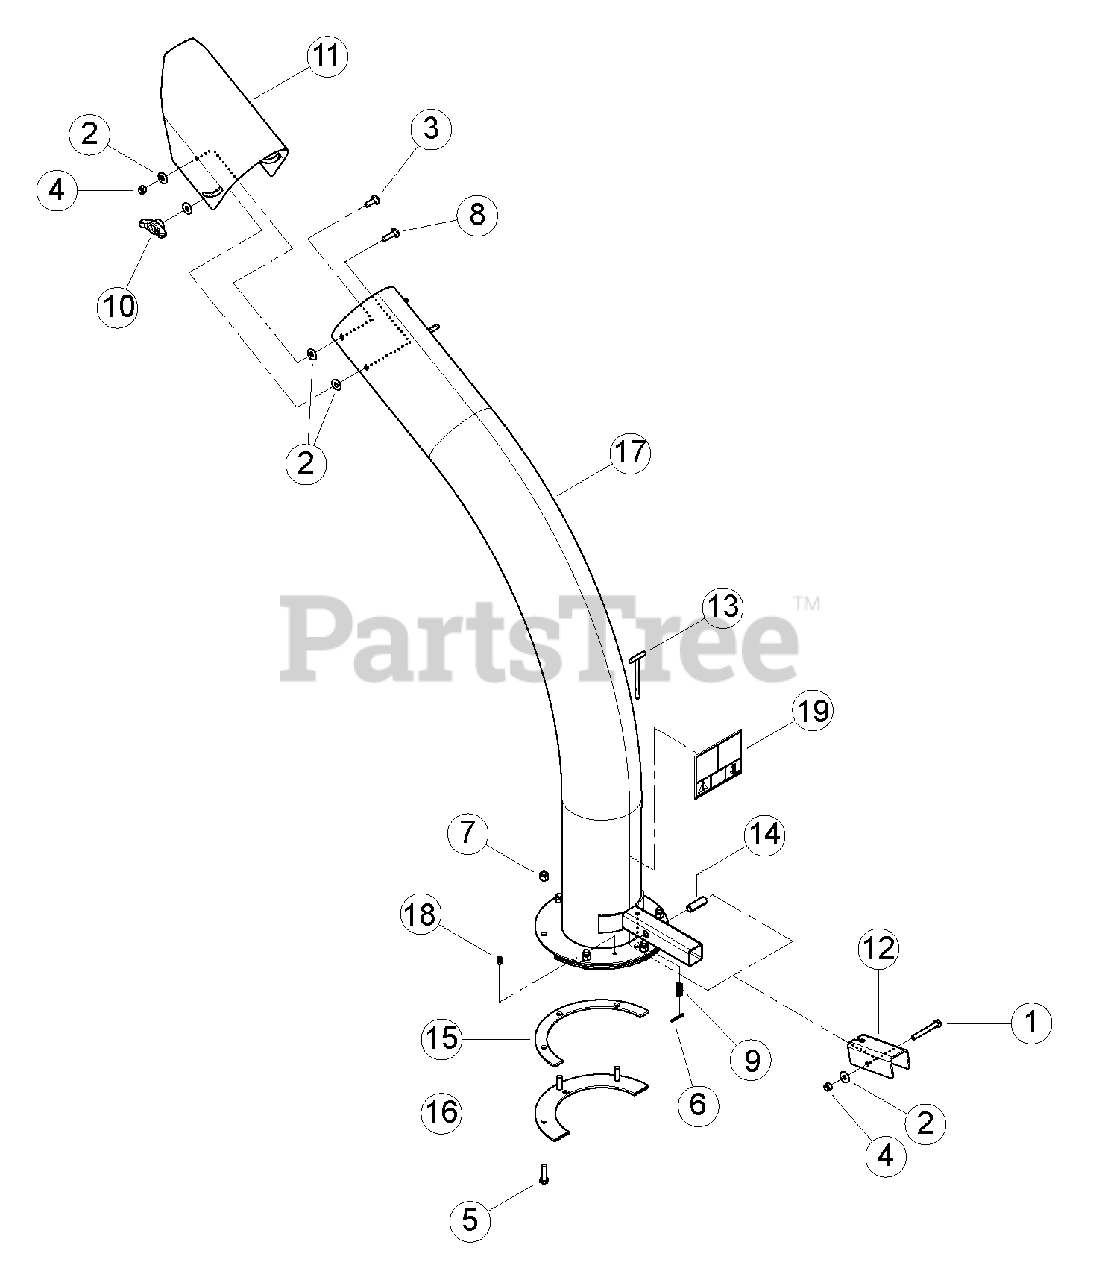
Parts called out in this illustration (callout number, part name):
1	BOLT, 5/16 X 2-1/2 HEX HD GR5 ZP
2	WASHER, 5/16 FLAT ZP
3	BOLT, 5/16 X 1 CRG GR5 ZP
4	NUT, 5/16 NE NYLOCK ZP
5	BOLT, 3/8 X 1-1/4 HEX HD GR5 ZP
6	PIN, 1/8 X 1.00 COTTER ZP
7	NUT, 3/8 NE NYLOCK ZP
8	BOLT, 5/16 X 1-1/4 CRG GR5 ZP
9	SPRING, LOCK COMPRESSION
10	KNOB, 5/16-18 UNC TEE W/LOCKING INSERT
11	DEFLECTOR, BLOWER-VAC DISCHARGE
12	LEVER, DISCHARGE LOCK
13	WELDMENT, DISCHARGE LOCK PIN
14	TUBE, DISCHARGE LOCK PIVOT
15	SPACER, DISCHARGE PIVOT
16	RING, DISCHARGE CLAMP
17	ASSEMBLY, 6 INCH DISCHARGE SERVICE PART
18	FITTING, 1/4 SELF-TAP GREASE
19	DECAL, DISCHARGE DEBRIS & LOCK
